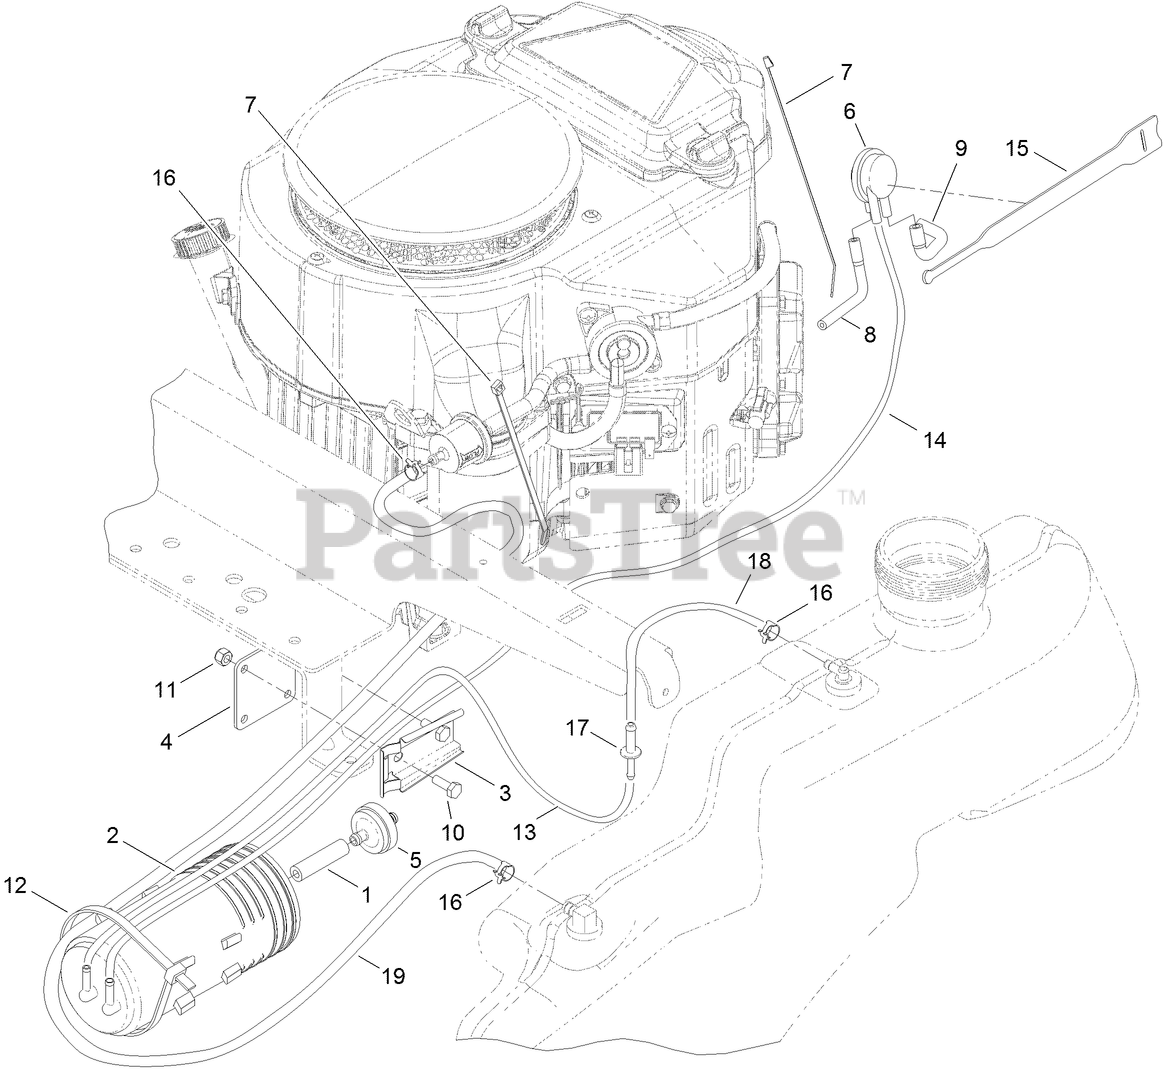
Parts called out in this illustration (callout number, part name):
1	HOSE-FUEL
2	CANISTER-CARBON, 800CC
3	BRACKET-CANISTER, CARBON
4	PLATE-ADAPTER
5	FILTER-FUEL, INLINE
6	VALVE-CONTROL, VACUUM
7	TIE-CABLE
8	HOSE-VENT, FORMED
9	HOSE-VENT, FORMED
10	SCREW-HH
11	NUT-LOCK, NI
12	TIE-CABLE
13	HOSE-FUEL
14	HOSE-FUEL
15	STRAP-VELCRO, CABLE TIE
16	CLAMP-HOSE
17	ADAPTOR-ORIFICE
18	HOSE-FUEL
19	HOSE-FUEL
